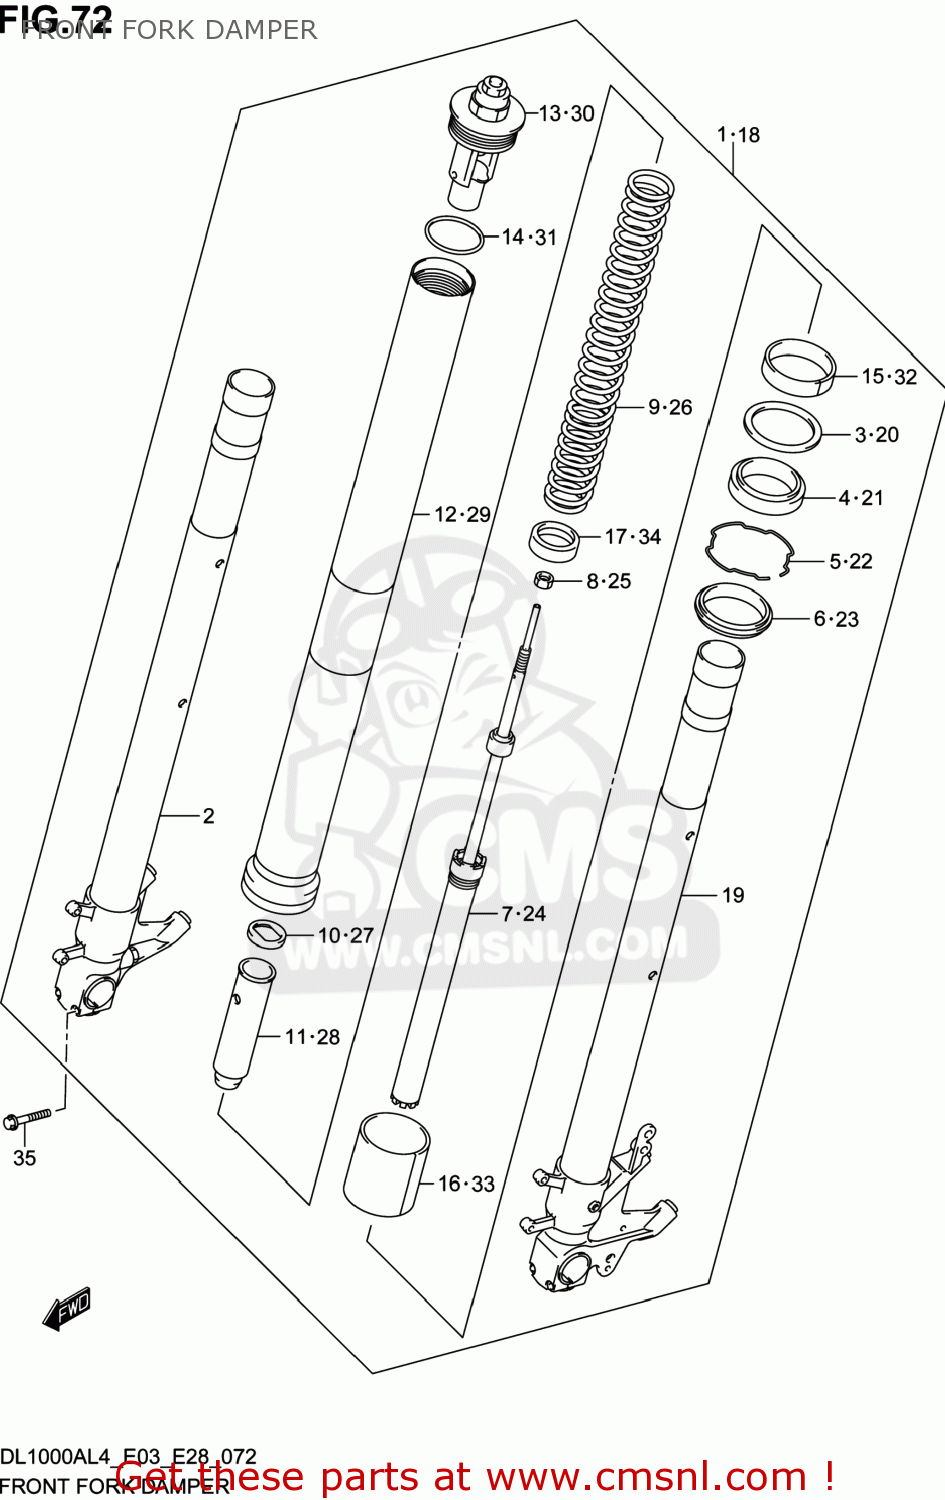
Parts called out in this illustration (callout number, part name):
1	DAMPER ASSY,FR FORK,R
2	TUBE,INNER,R
3	WASHER
4	SEAL,OIL
5	RING,STOPPER
6	SEAL,DUST
7	CYLINDER
8	NUT,ROD
9	SPRING
10	GUIDE,SPRING
11	SPACER,SPRING
12	TUBE,OUTER
13	CAP
14	O RING
15	PISTON
16	SLIDEMETAL
17	SEAT,SPRING
18	DAMPER ASSY,FR FORK,L
19	TUBE,INNER,L
20	WASHER
21	SEAL,OIL
22	RING,STOPPER
23	SEAL,DUST
24	CYLINDER
25	NUT,ROD
26	SPRING
27	GUIDE,SPRING
28	SPACER,SPRING
29	TUBE,OUTER
30	CAP
31	O RING
32	PISTON
33	SLIDEMETAL
34	SEAT,SPRING
35	BOLT
